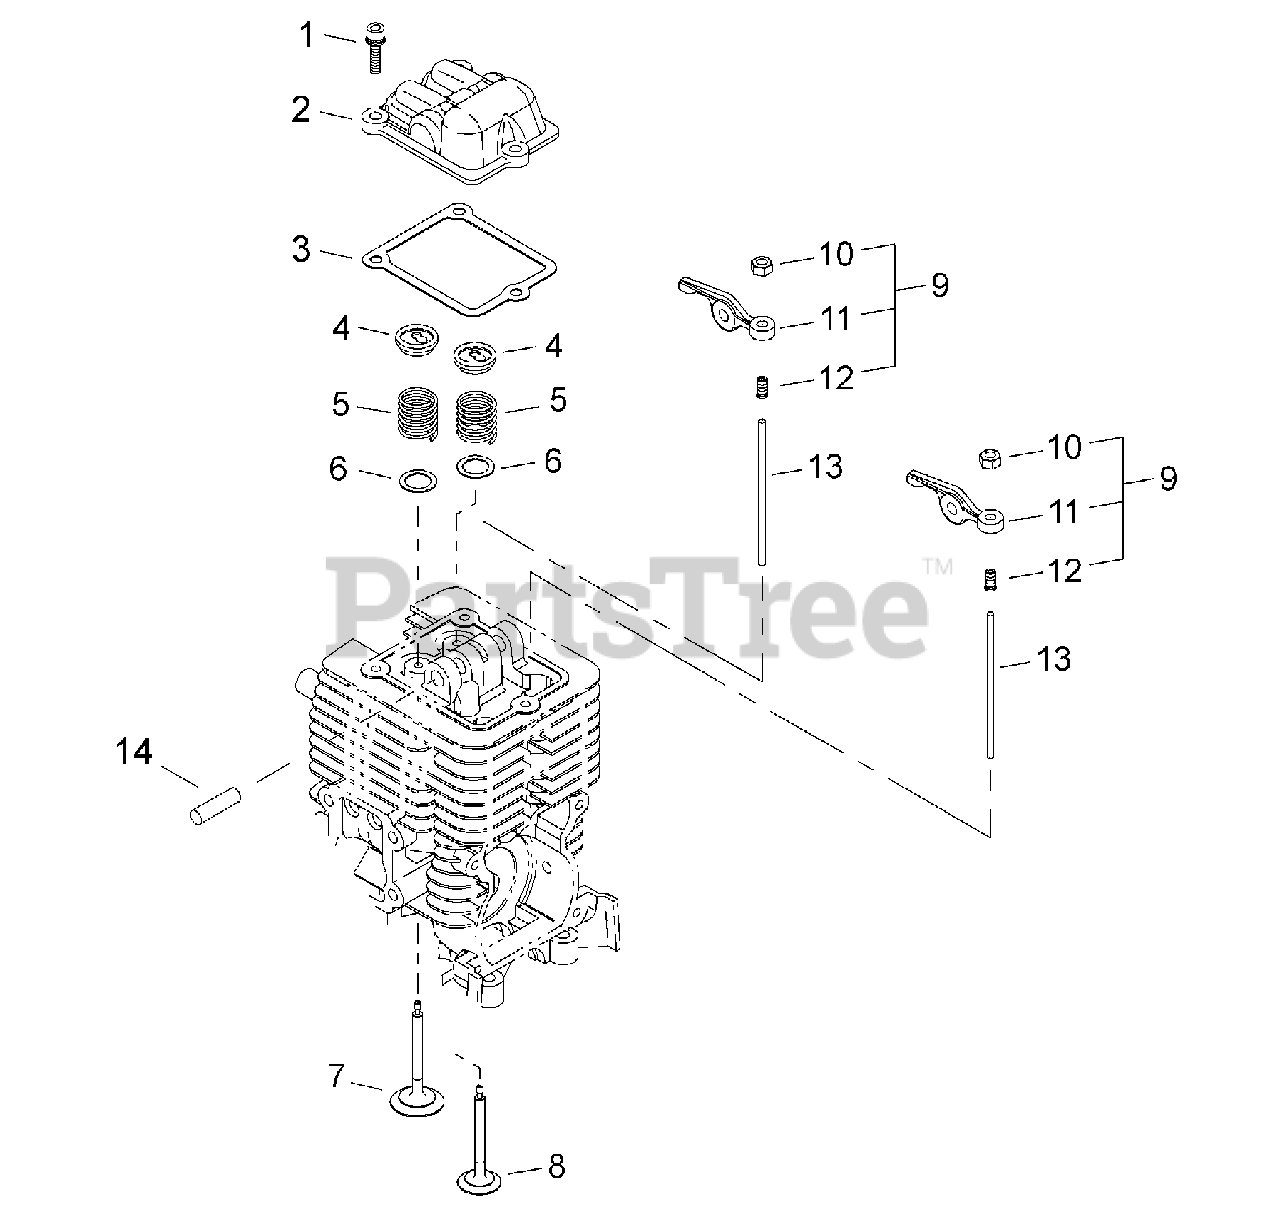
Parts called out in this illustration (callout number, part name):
1	BOLT M4×14
2	COVER, ROCKER ARM
3	GASKET, ROCKER ARM
4	RETAINER, VALVE
5	SPRING, VALVE
6	WASHER, VALVE 9
7	VALVE, INTAKE
8	VALVE, EXHAUST
9	ARM ASSY, ROCKER
10	NUT, ADJUSTER LOCK 5
11	ARM, ROCKER
12	SCREW, ADJUSTER
13	PUSHROD
14	SHAFT, ROCKER ARM Ø5×37.8 MM
